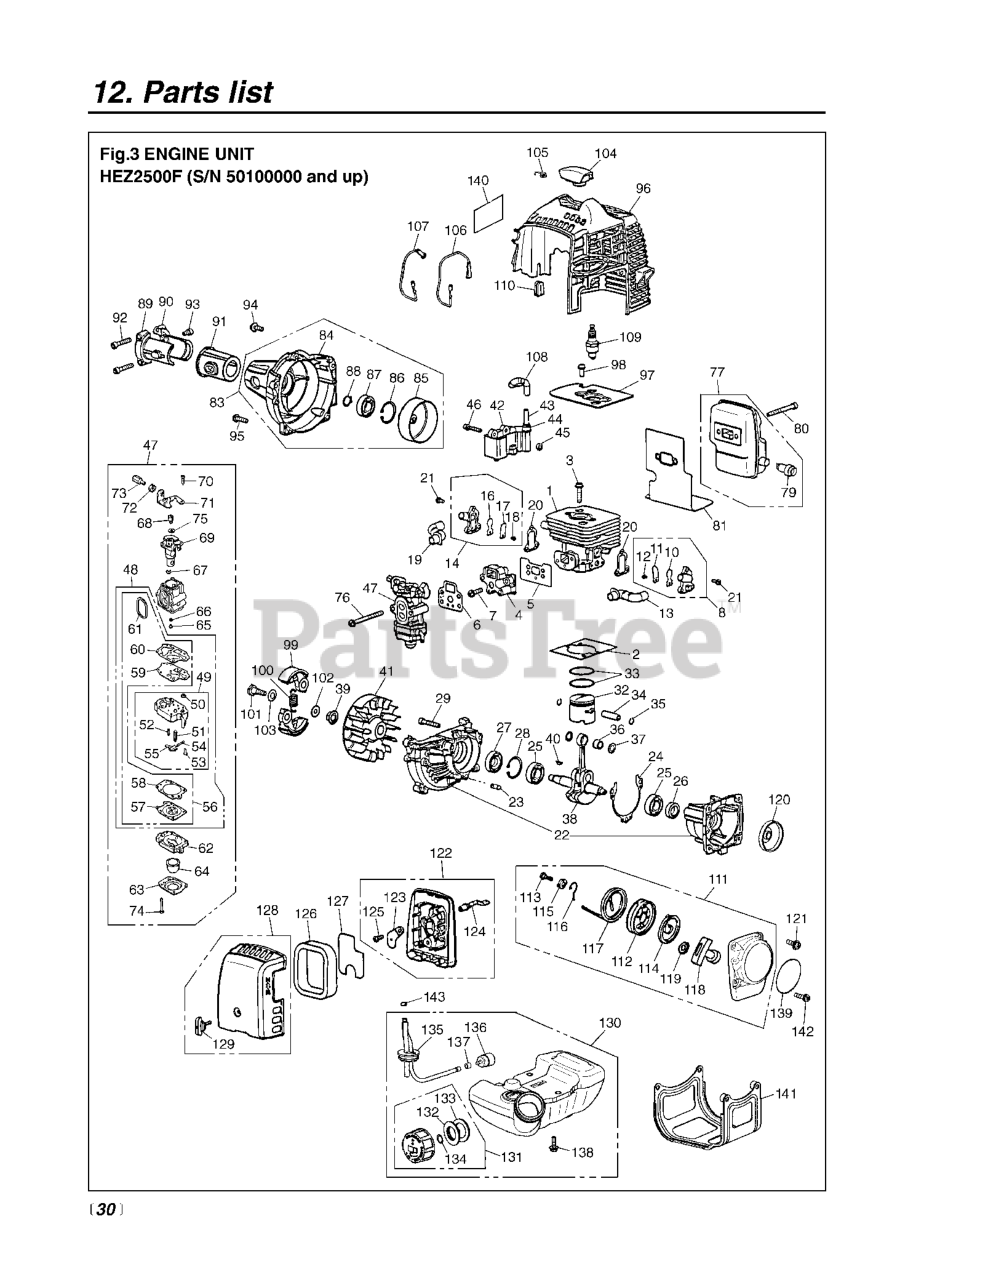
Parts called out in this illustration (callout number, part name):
1	CYLINDER (RPLS 481012111)
4	INSULATOR
5	GASKET.INSU
8	REED VALVE (RPLS 848F301601)
10	REEDVALVE
13	PIPE.AIR
14	REED VALVE(F)(R1611,481016200)
16	REEDVALVE
19	PIPE.AIR
22	CRANKCASE-C
23	PIN
24	GASKET.CASE
27	SEAL
33	RING.PISTON
34	PIN***
39	NUT
40	KEY
44	CAP
45	SPACER
47	CARBURETOR ASSY***
48	REBUILD KIT***
49	BODY-A
50	RedMax TBD
51	RedMax TBD
52	RedMax TBD
53	RedMax TBD
54	RedMax TBD
55	RedMax TBD
56	GASKET KIT
57	RedMax TBD
58	RedMax TBD
59	RedMax TBD
60	RedMax TBD
63	1OVER
67	RING
68	SWIVEL
69	RedMax TBD
70	SCREW
71	BRACKET
72	NUT
73	ADJUSTER
75	WASHER
77	MUFFLER
79	ARRESTER
80	BOLT, M5 x 50 (RPLS 125230550)
81	GASKET (RPLS T150115410,5210)
83	COVER-C
84	COVER.FAN
87	BEARING
89	BRACKET(A)-24
90	BRACKET(B)-24
96	COVER.ENGINE
97	PLATE, CYLINDER(RPL-481012310)
104	CAP
107	CORD.EARTH
108	TUBE (RPLS 263072210)
109	PLUG, SPARK (RPLS 481073110)
111	RECOIL-A
114	SPRING, SPIRAL
115	COLLAR
116	SWING ARM
119	PLATE.STOPPER
122	BODY-A
123	PLATE.CHOKE
125	SCREW
128	AIR FILTER COVER
131	CAP A
132	HOLDER-A
135	PIPE-C
136	FILTER ASSY
139	RedMax TBD
141	GUARD (RPLS 481031910,11)
143	CLIP
